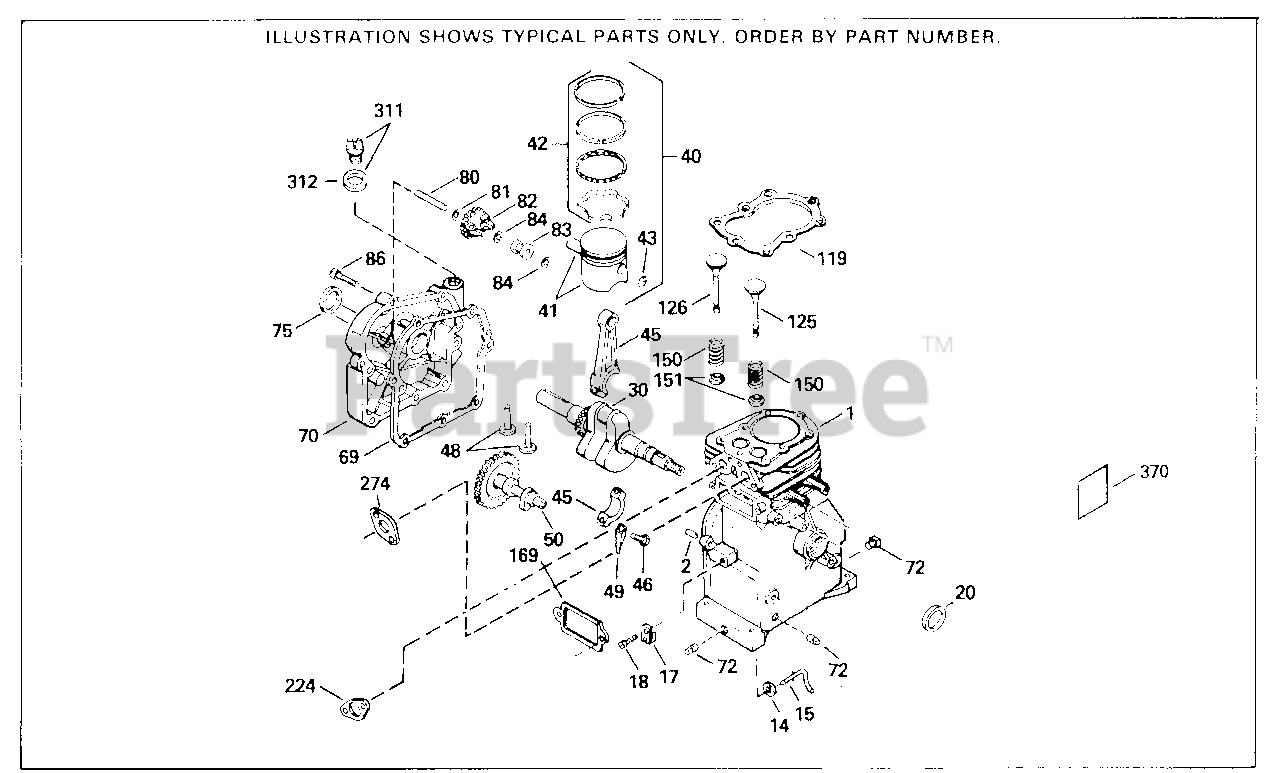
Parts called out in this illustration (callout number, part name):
1	"Cylinder (Incl. 2, 20, 72 & 72A) 2-5/ 8"
2	Dowel Pin
14	Flat Washer
15	Rod, Governor
17	Clamp, Governor lever
18	Screw, 8-32 x 5/16"
20	Seal, Oil
30	Crankshaft
40	Piston, Pin & Ring Set (.020" OS) (In cl. 41, 42 & 43)
40	Piston, Pin & Ring Set (Std.) 2-5/8"
40	Piston, Pin & Ring Set (.010" OS)
41	Piston & Pin Assembly (Std.) (Incl. 4 3)(2-5/8")
41	Piston & Pin Assembly (.010" OS) (Inc l. 43)
41	Piston & Pin Assembly (.020" OS) (Inc l. 43)
42	Ring Set (Std.) (2-5/8" Bore)
42	Ring Set (.010" OS)
42	Ring Set (.020" OS)
43	Piston Pin Retaining Ring
45	Rod Assy., Connecting (Incl. 46 & 49)
46	Bolt, Connecting rod
48	Valve Lifter
49	Dipper, Oil
50	Camshaft
69	Cylinder Cover Gasket
70	Cover, Cylinder (Incl. 75 & 80)
72	Oil Drain Plug (Sq. hd., 1/4-18)
75	Oil Seal
80	Shaft, Mechanical governor
81	Washer, Flat
82	Gear, Governor (Incl. 81)
83	Spool, Governor
84	Retaining Ring
86	Screw, 1/4-20 x 1-1/4"
119	Gasket, Cylinder head
125	Exhaust Valve (Std.) (Incl. 151)
125	Exhaust Valve (1/32" OS) (Incl. 151)
126	Intake Valve (Std.) (Incl. 151)
126	Intake Valve (1/32" OS) (Incl. 151)
150	Spring, Valve
151	Cap, Valve spring
169	Gasket, Valve cover
224	Gasket, Intake
274	Intake Pipe Gasket
311	Oil Fill Plug (Incl. 312) also availa ble in Packaged Part #740079
312	Oil Fill Plug Gasket
370	Decal, Instruction
